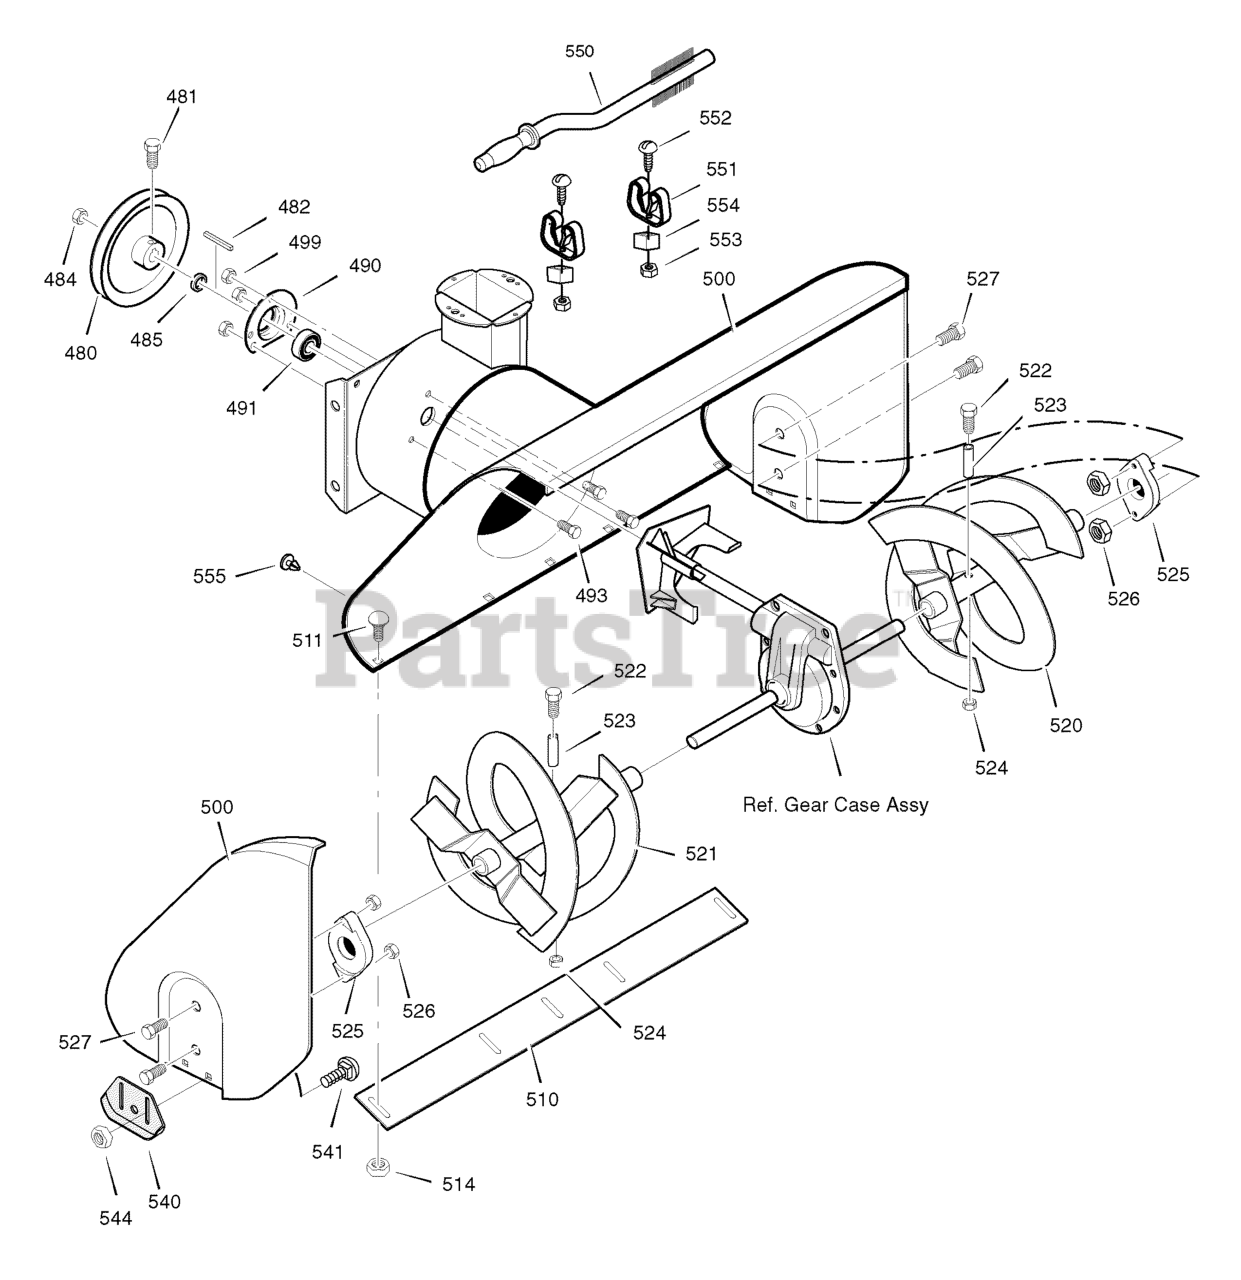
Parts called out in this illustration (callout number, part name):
481	SCREW, 5/16-18 X .62
482	KEY, SQUARE 3/16 X 3/4
484	NUT.50-20 HEX FLG SERLKZ
485	SPACER, FRICTION PULLEY
490	RETAINER, BALL BEARING
491	BEARING, BALL
493	BOLT, HEX 5/16-18 X .50
499	NUT, 5/16-18 HEXWDFLLK
500	HOUSING, ASSEMBLY
510	BLADE, SCRAPER
511	BOLT, 5/16-18 X .75
514	NUT, 5/16-18
520	AUGER, ASSEMBLY, LH
521	AUGER, ASSEMBLY, RH
522	SCREW, 1/4-20 X 1.75
523	SPACER, SLEEVE
524	NUT, 1/4-20
525	BEARING, FLANGE
526	NUT, 5/16-18
527	SCREW, 5/16-18 X .75
540	SKID, HEIGHT ADJUST
541	BOLT, 5/16-18 X .75
544	NUT, 5/16-18
550	BRUSH, CLEANOUT
551	CLIP, RETAINER
552	SCREW
553	NUT
555	PLUG-PANEL .32 X .48L BLACK
